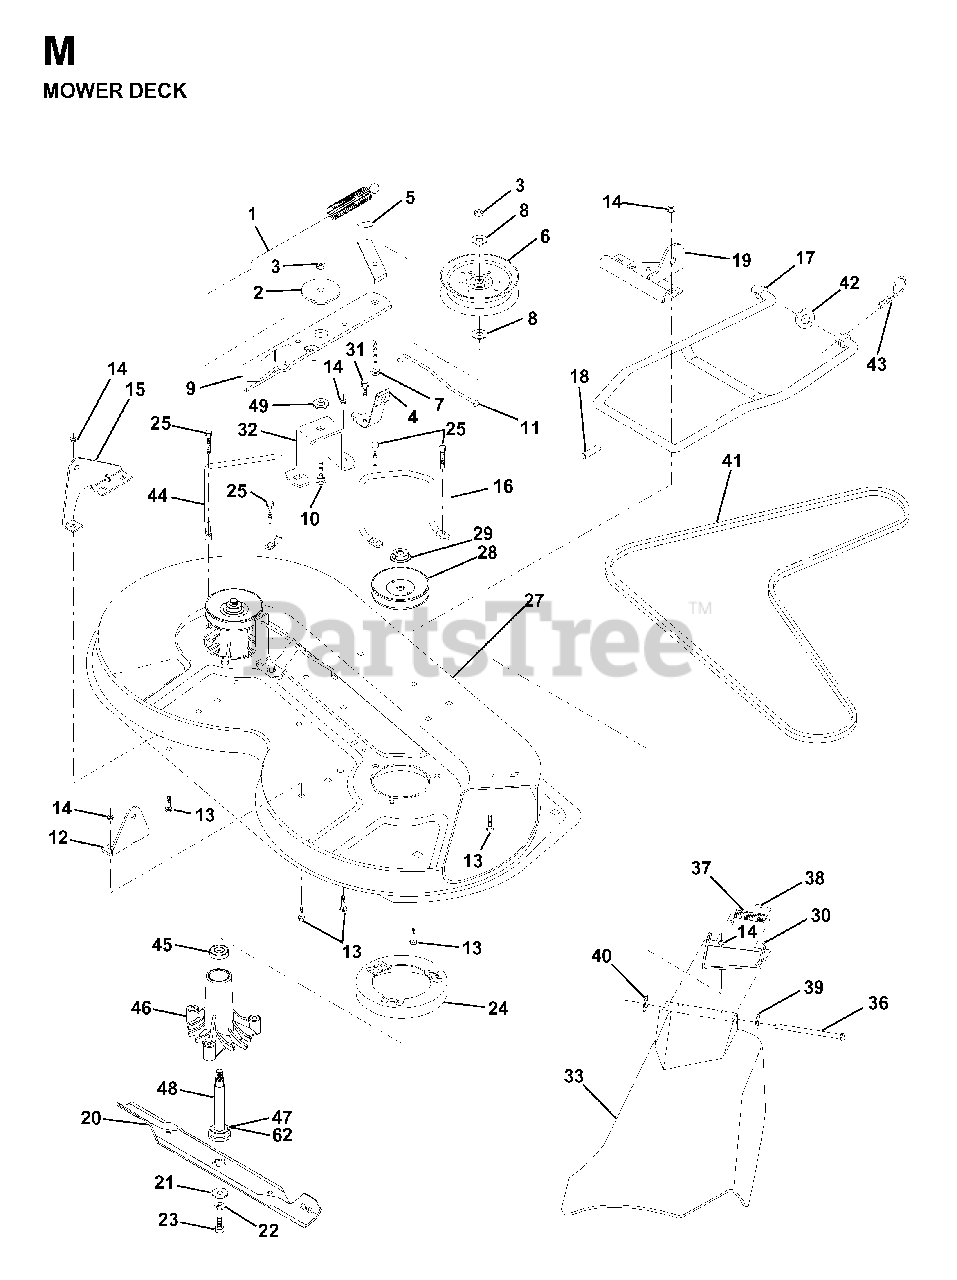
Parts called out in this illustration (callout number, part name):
1	SPRING-MOWER CLUTCH
2	SPACER RETAINER
3	LOCKNUT
4	BRAKE ASSEMBLY
5	IDLER BELT GUIDE
6	PULLEY IDLER
7	BOLT
8	WASHER
9	IDLER ARM ASSY
10	BOLT.3/8-14X1.25
11	BRAKE ROD
12	BRKT LIFT REAR
13	BOLT
14	LOCKNUT
15	BRKT LIFT REAR LH
16	BELT KEEPER
17	MOWER LINK STABILIZER
18	PIN GROOVE
19	BRKT LINK STABILIIZER
21	WASHER.BLADE
22	LOCKWASHER
23	BLADE BOLT
24	STRIPPER
25	SCREW THDROL ROLLING WASHER HD
27	MOWER HOUSING
28	PULLEY, MANDREL
29	NUT
30	BRACKET ASM DEFLECTOR
32	SUPT,IDLER ARM
33	DEFLECTOR
36	HINGE ROD
37	SPRING TORSION
38	CAP-SLEEVE LT
39	WASHER
40	NUT PUSH M
42	WASHER
43	SPRING RETAINER
44	KEEPER LH
46	HSG MANDREL
47	BEARING
48	SHAFT ASM VENT
49	HARDENED WASHER
62	WASHER FELT
